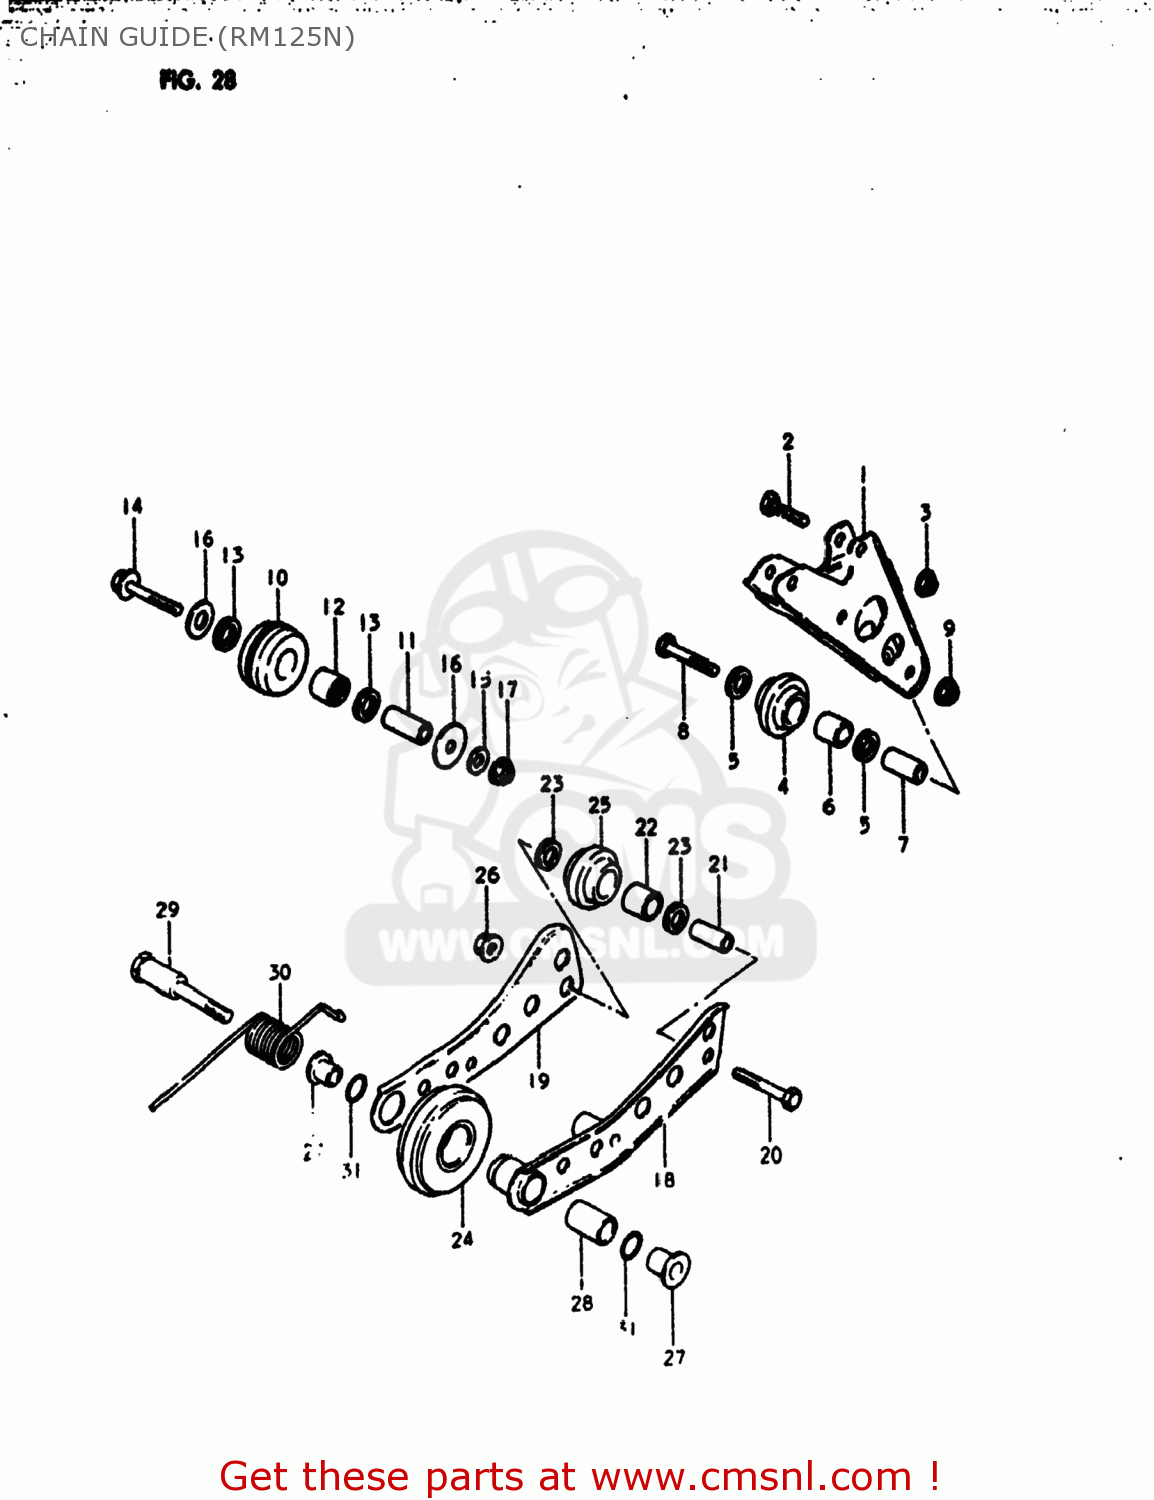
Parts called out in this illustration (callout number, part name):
1	GUIDE,DRIVE CHAIN
2	BOLT
3	NUT 6MM
4	ROLLER,CHAIN TENSIONER LWR
5	SEAL,OIL(10X14.4X3.5)
6	SPACER,CHAIN GUIDE
7	SPACER(6.2X10X22.5)
8	BOLT 6X35
9	NUT
10	ROLLER,CHAIN GUIDE
11	SPACER(6.2X10X22.5)
12	BEARING(10X14X15)
13	SEAL,OIL(10X14.4X3.5)
14	BOLT
15	WASHER
16	WASHER(6.5X18X1)
17	NUT 6MM
18	TENSIONER,CHAIN
19	PLATE,CHAIN TENSIONER
20	BOLT 6X35
21	SPACER(6.2X10X22.5)
22	SPACER,CHAIN GUIDE
23	SEAL,OIL(10X14.4X3.5)
24	ROLLER,CHAIN GUIDE
25	ROLLER,CHAIN TENSIONER LWR
26	NUT
27	SPACER,CHAIN TENSIONER
28	BUSHING,CHAIN TENSIONER
29	BOLT
30	SPRING
31	O RING(D:1.3,ID:9.6)
